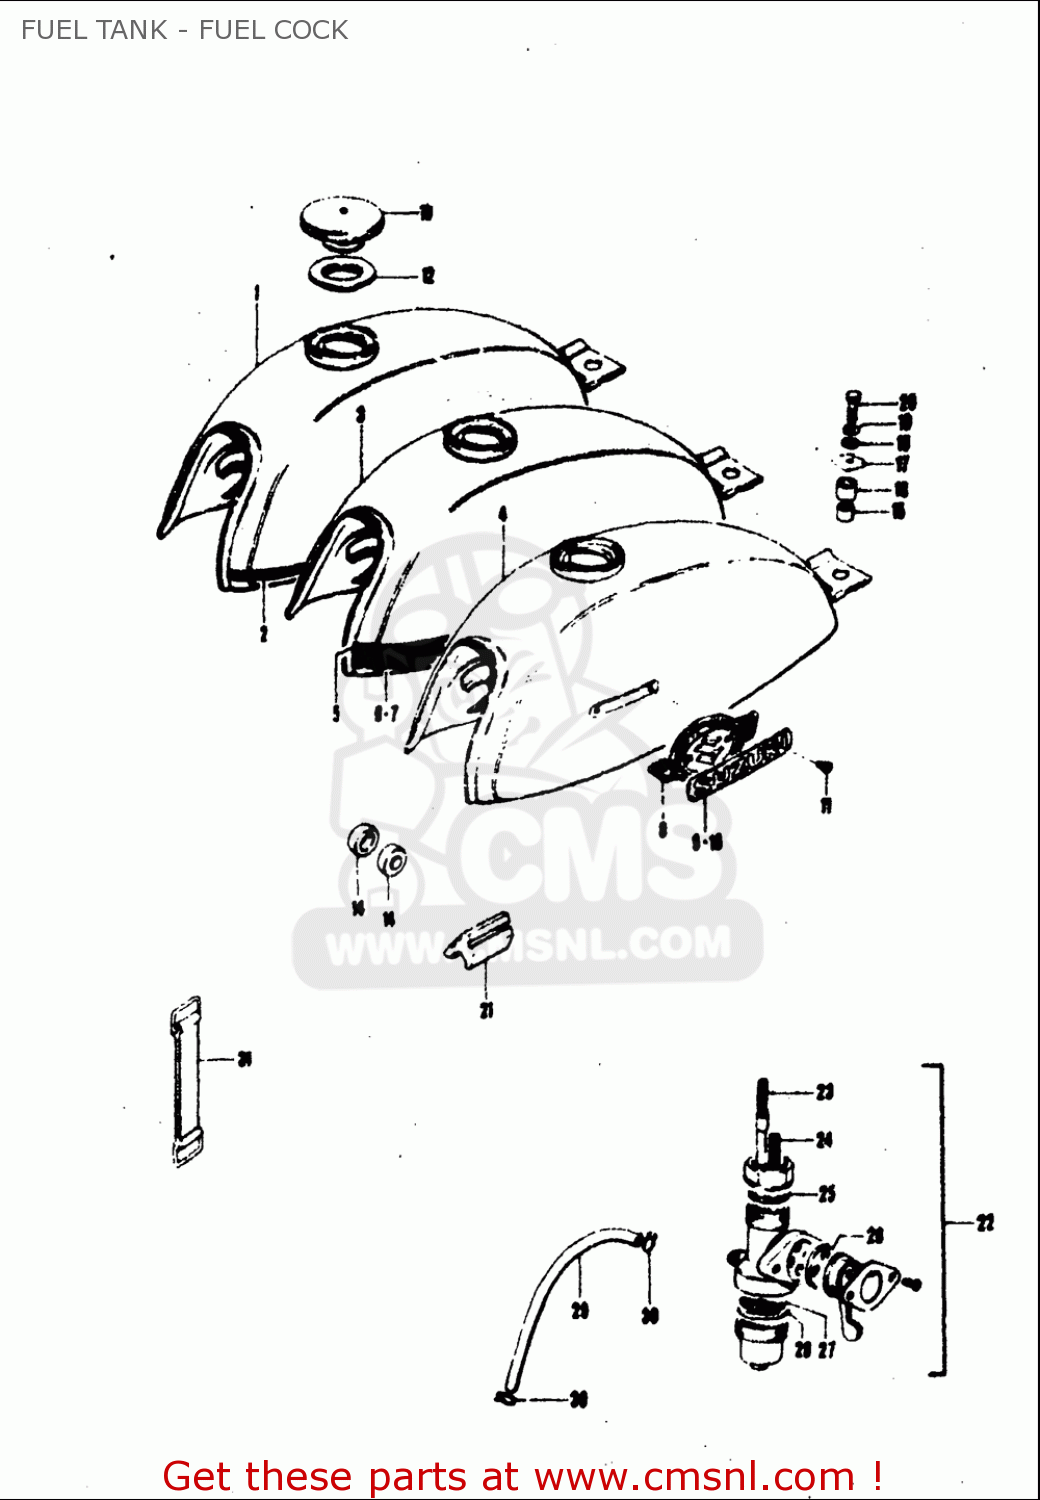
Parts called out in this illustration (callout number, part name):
18	WASHER(8.5X28X1.6)
19	WASHER,LOCK
20	BOLT
22	COCK ASSY,FUEL
25	GASKET,FUEL COCK (NAS)
26	GASKET,LEVER (NAS)
27	NET,STRAINER
28	GASKET,STRAINER CUP (NAS)
29	HOSE(5X8.2X600)
31	BAND
